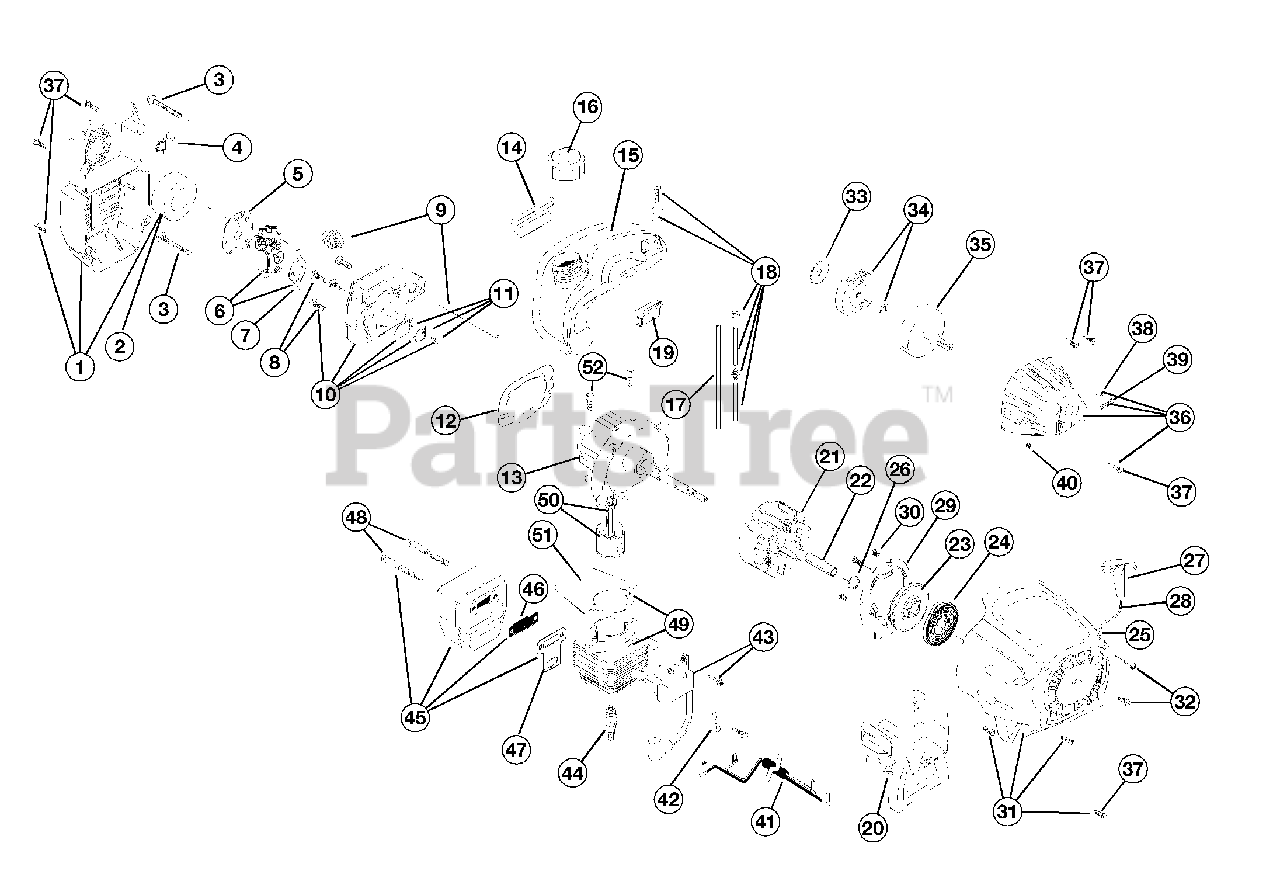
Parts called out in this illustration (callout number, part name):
1	Air Cleaner/Muffler Cover Assembly
2	Air Cleaner Filter
3	Carburetor Mounting Screw Assembly
4	Choke Extension
5	Choke Plate
6	Carburetor Assembly
7	Carburetor Gasket
8	Carb Mount Screw
9	Primer and Hose Assembly
10	Carb Mount Assembly
11	Reed Assembly
12	Carburetor Mount Gasket
13	Crank Case Service Assembly
14	Rear Mounting Pad
15	Fuel Tank Assembly
16	Fuel Cap Assembly
17	Fuel Return Line
18	Fuel Line Assembly
19	Front Mounting Pad
20	Shroud Extension & Stand
21	Flywheel Assembly
23	Recoil Pulley
24	Recoil Spring
25	Rope Guide
26	Pulley Retainer
27	Pull Handle
29	Pressure Plate Assembly
30	Plate Screw
31	Starter Housing Assembly
32	Housing Screw
33	Clutch Washer
34	Clutch Rotor Assembly
35	Clutch Drum Assembly
36	Clutch Cover Assembly
37	Cover Screw
38	Anti-Rotation Screw
39	Clamping Screw
40	Clamping Nut
41	Wire Leads and Sleeve
42	Ground Tab
43	Module Assembly
45	Muffler Assembly
46	Spark Arrestor Screen
47	Exhaust Gasket
48	Muffler Mounting Bolt Assembly
49	Cylinder Assembly
50	Piston and Rod Assembly
51	Cylinder Gasket
52	Cylinder Bolt
